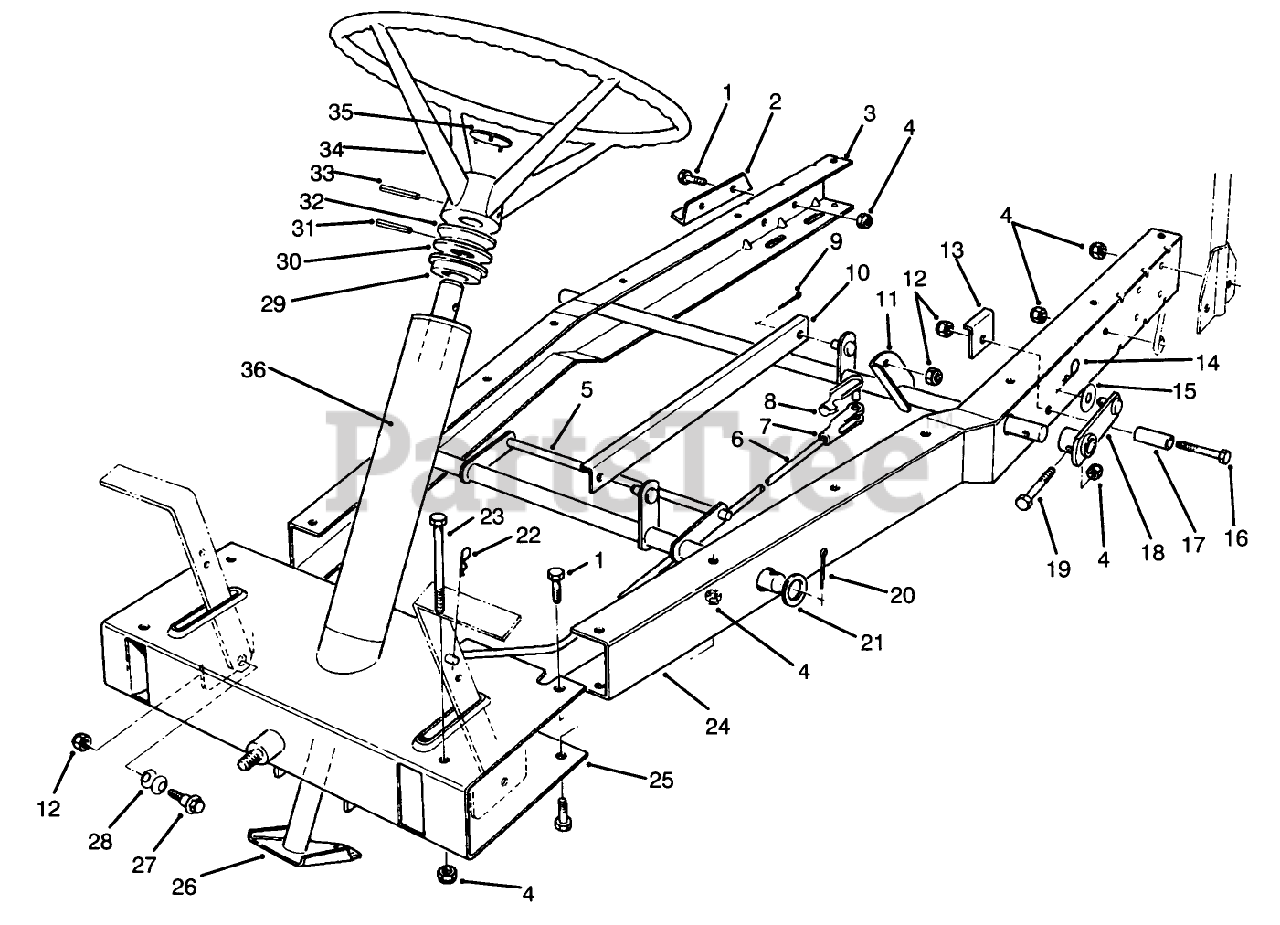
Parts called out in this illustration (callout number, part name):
1	SCREW-HH
2	MOUNT-AXLE BEARING
4	NUT-LOCK, NI
5	FRT DECK LIFT WA
6	ROD-CLUTCH
7	CLEVIS-ADJ
8	Assembly-Pin, Clevis
9	PIN-COTTER
10	LINK-HOC BRACKET
11	TUBE ASM-REAR SUPPORT
12	NUT-LOCK, NI
13	DECK STOP BRACE
14	PIN-HAIR
15	WASHER
16	SCREW-HH
17	SPACER-STOP,DECK
18	HOC LEVER WA
19	AXLE MTG BOLT
20	PIN-COTTER
21	WASHER-FLAT
22	PIN-COTTER
23	SCREW-HH
24	FRAME-CHANNEL LH *
27	BOLT-SHOULDER
28	WASHER-BELLEVILLE
30	WASHER-STEERING
31	PIN-ROLL
32	SPACER-STEERING
33	PIN-ROLL
34	STEERING WHEEL ASM
35	INSERT - STEERING WHEEL, LAWNBOY
36	DECAL - STEERING COLUMN
